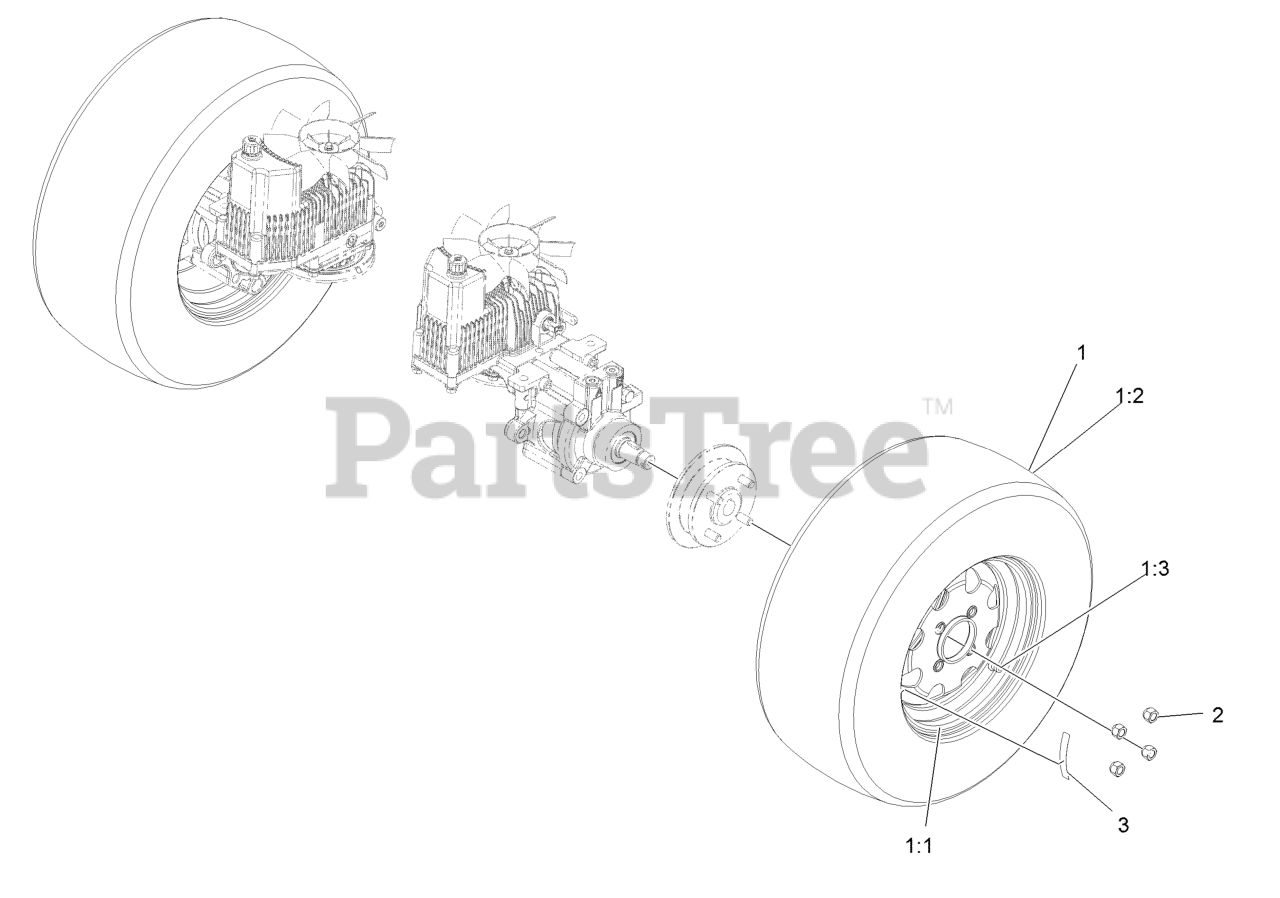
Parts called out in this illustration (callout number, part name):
1	Wheel And Tire ASM
1:1	Rim ASM
1:2	Tire
1:3	Stem-Valve
2	Nut-Lug 1/2-20
3	Decal-Torque, Wheel Hub Lug
